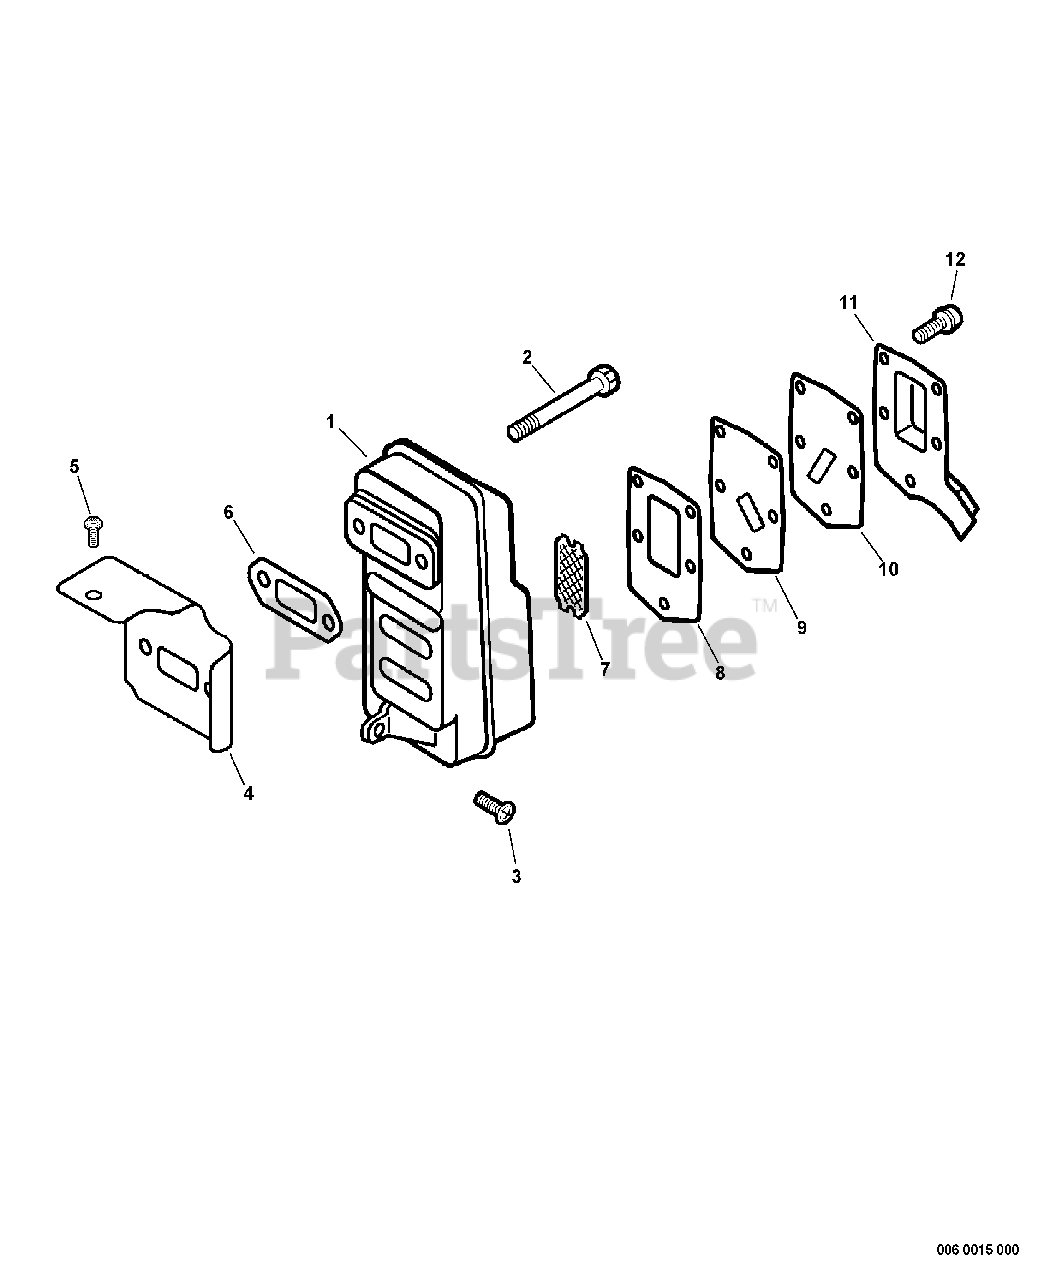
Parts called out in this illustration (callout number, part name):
1	MUFFLER
2	BOLT 6×20
3	BOLT 5×20
4	COVER, CYLINDER
5	SCREW 5×10
6	GASKET, MUFFLER
7	SCREEN, SPARK ARRESTER
8	GASKET, EXHAUST
9	GASKET, EXHAUST
10	GASKET, EXHAUST
11	GUIDE, EXHAUST
12	SCREW 4×14
